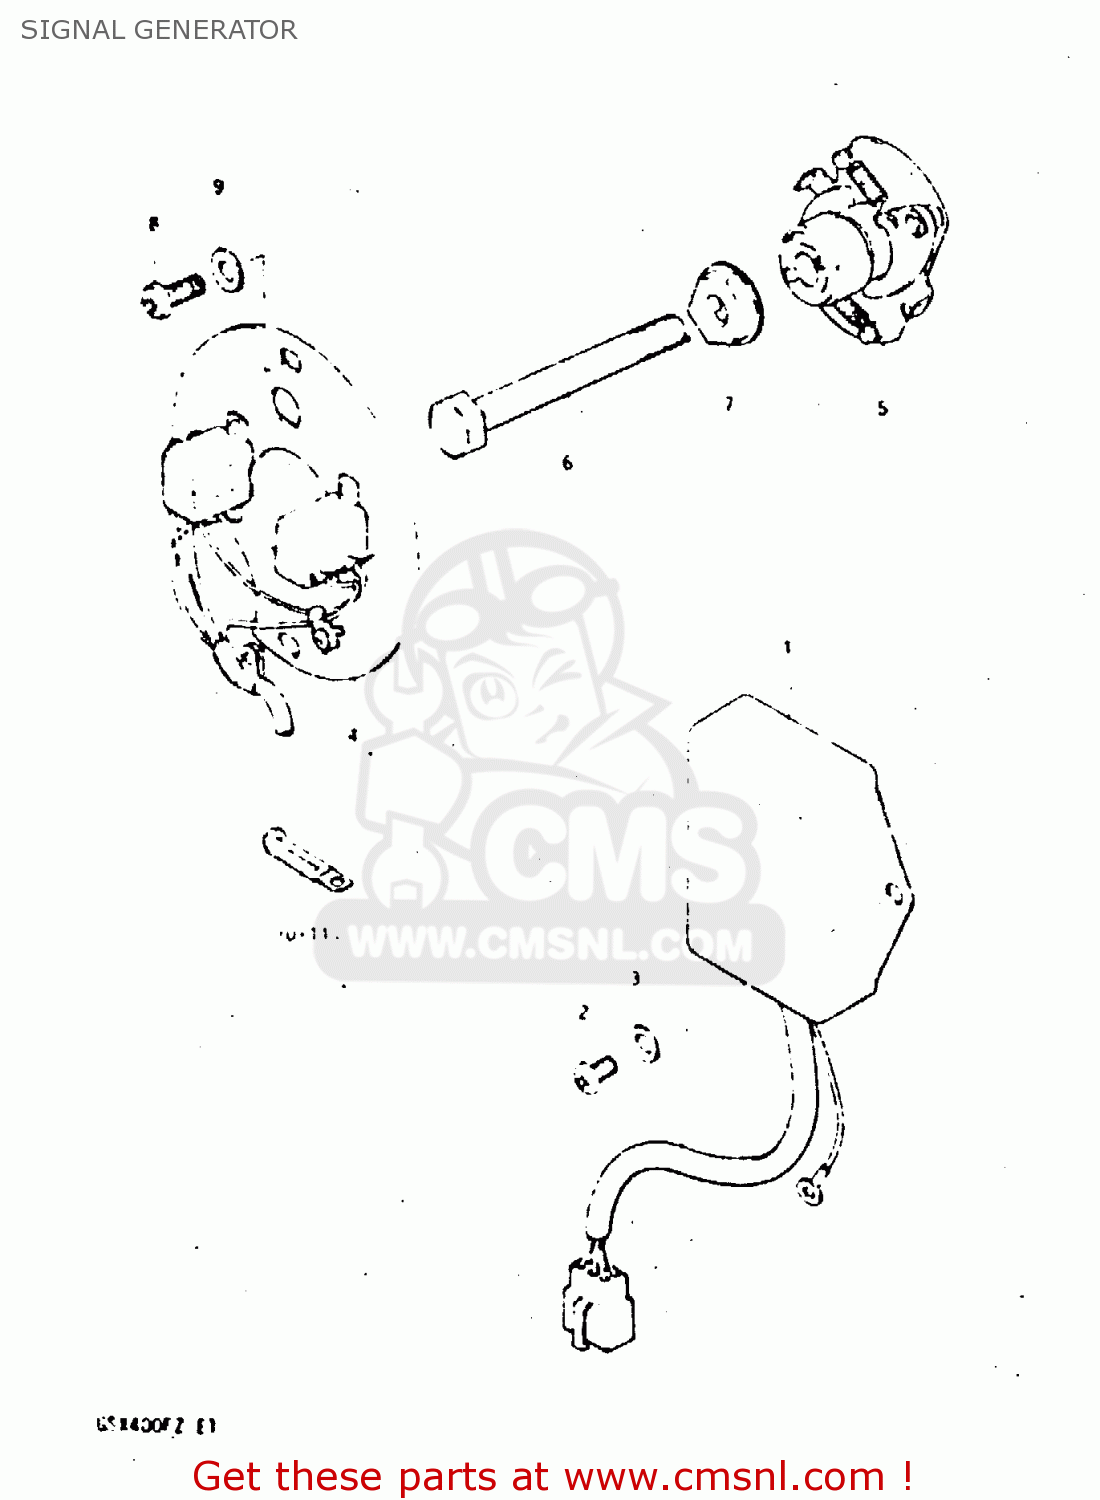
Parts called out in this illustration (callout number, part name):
1	IGNITOR UNIT
2	SCREW
3	WASHER
4	SIGNAL GENERATOR ASSY
5	GOVERNOR ASSY, ADVANCE
6	BOLT
7	WASHER
8	SCREW(5X12)
9	WASHER
10	CLAMP L:35
11	CLAMP
